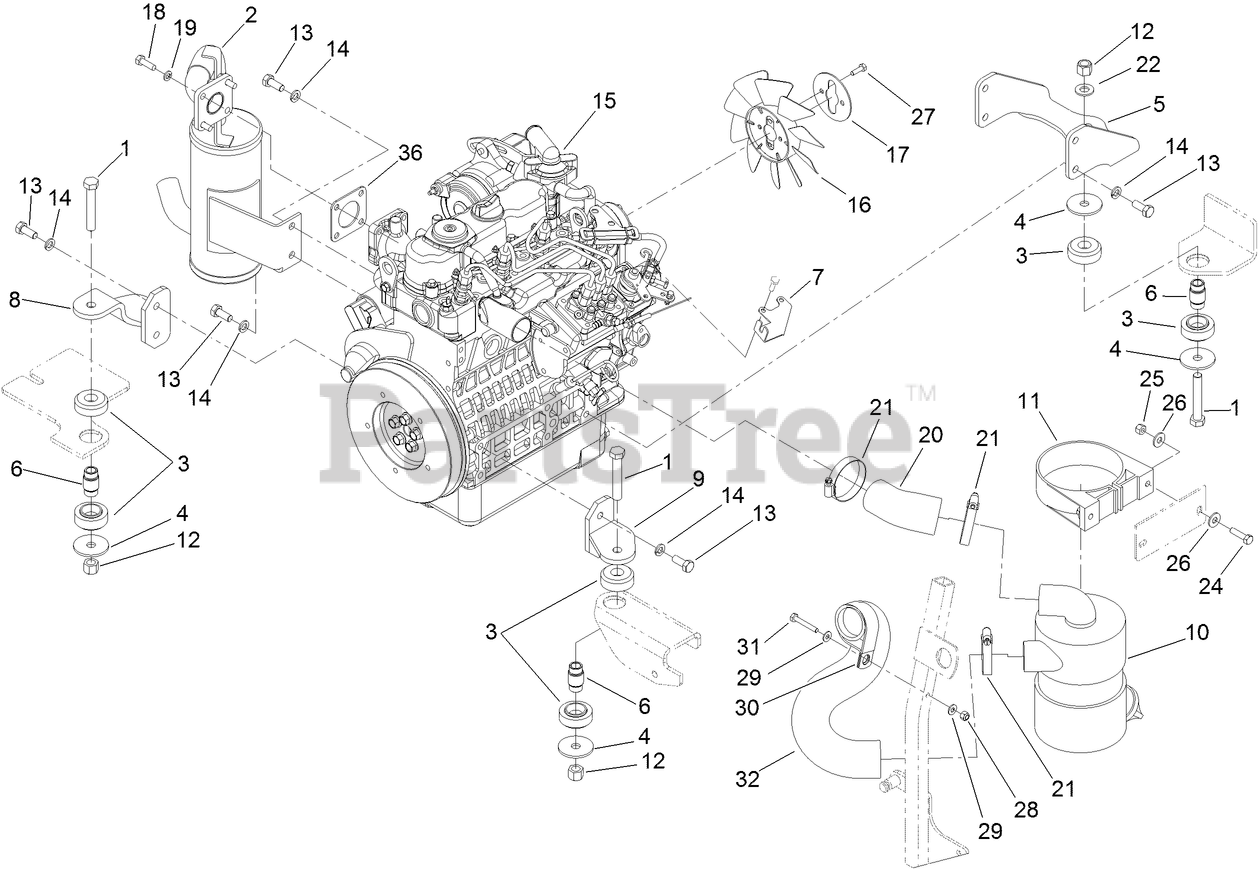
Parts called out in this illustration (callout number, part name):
1	SCREW-HH
2	MUFFLER
3	MOUNT-ISOLATION ASM
4	WASHER-LARGE
5	BRACKET-ENGINE MOUNT, REAR
6	SPACER
7	BRACKET-THROTTLE
8	SUPPORT-ENGINE, RH
9	SUPPORT-ENGINE, LH
10	AIR CLEANER ASM
11	BRACKET-MOUNTING
12	NUT-LOCK, NI
13	SCREW-HH
14	WASHER-LOCK, SPRING
15	ENGINE-KUBOTA
17	PLATE-REATAINER, FAN
18	SCREW-HH
19	WASHER-LOCK
20	HOSE-INTAKE, AIR CLEANER
21	CLAMP-HOSE
22	WASHER-FLAT
24	SCREW-HH
25	NUT-LOCK, NI
26	WASHER-PLAIN
27	SCREW-HH
28	NUT-LOCK, NI
29	WASHER-FLAT
30	CLIP-LOOM
31	SCREW-HH
32	HOSE-INTAKE, ENGINE
36	GASKET-MUFFLER
